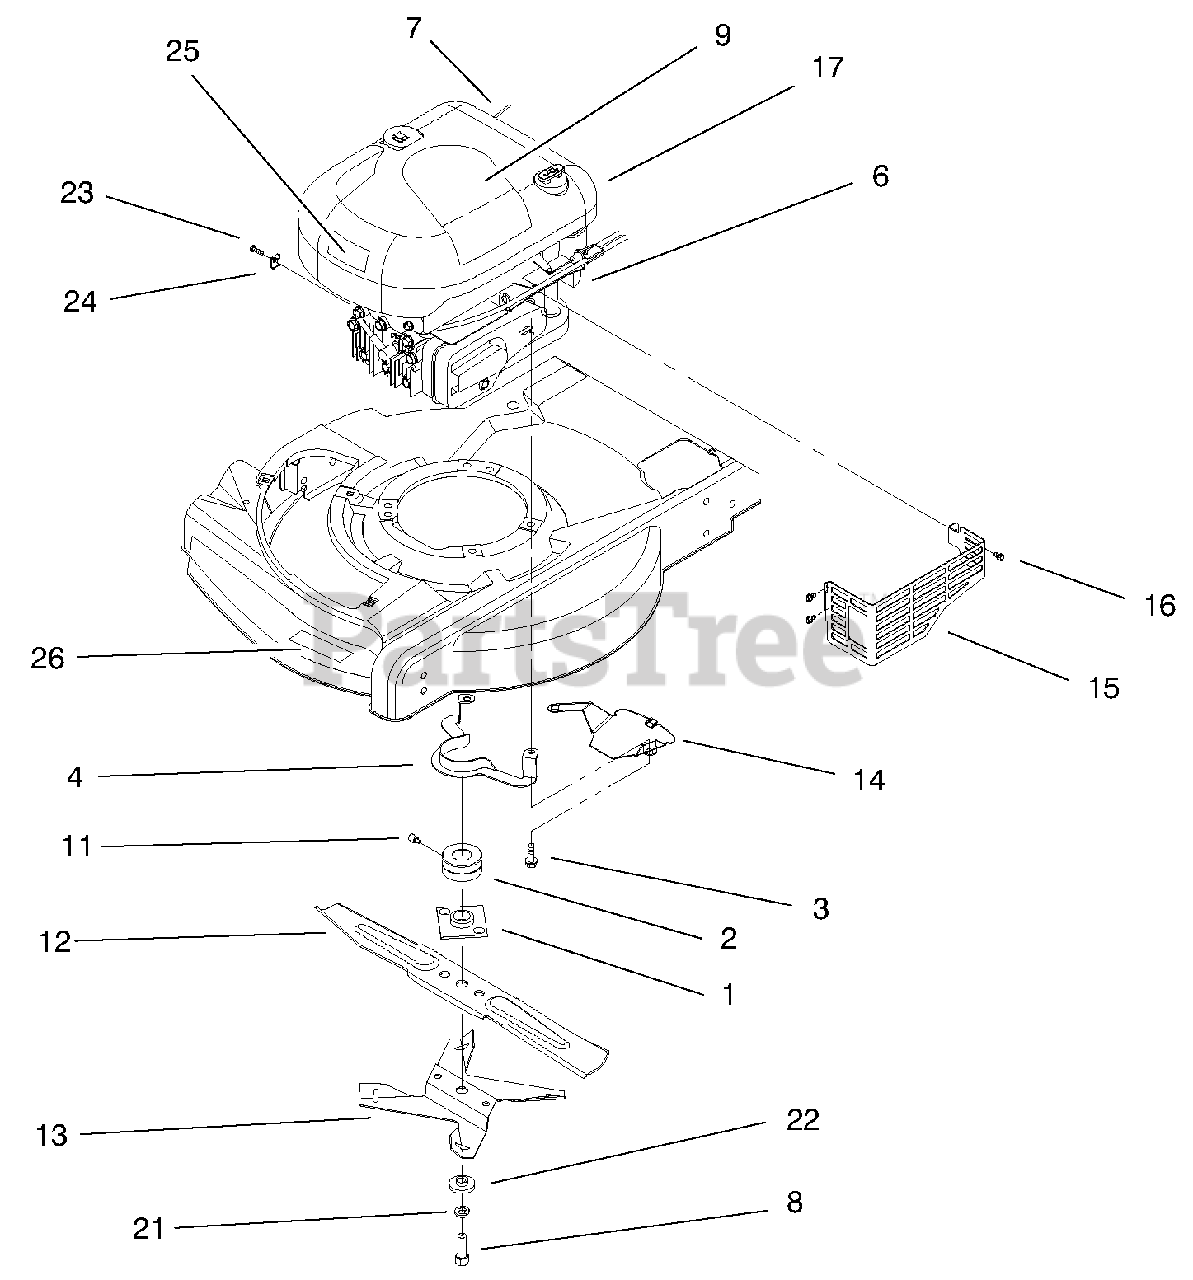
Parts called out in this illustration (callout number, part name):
1	ASM-Plate & Collar
2	Pulley-Engine
3	Screw-Engine Mount
4	Guide-Belt
6	ASM-Engine
7	Rope-Stop
8	Bolt-Blade
9	Decal-Recoil
11	Screw-Set
12	Blade-21" Whirl
13	Fan-Mulching
14	Shield-Grass
15	Shield-Muffler
16	Screw-HWHTF
17	Shroud-Engine
21	Washer-Lock
22	Spacer-Blade
23	Screw-Clamp
24	Clamp-Casing
25	Applique-Shroud
26	Decal-Deck
